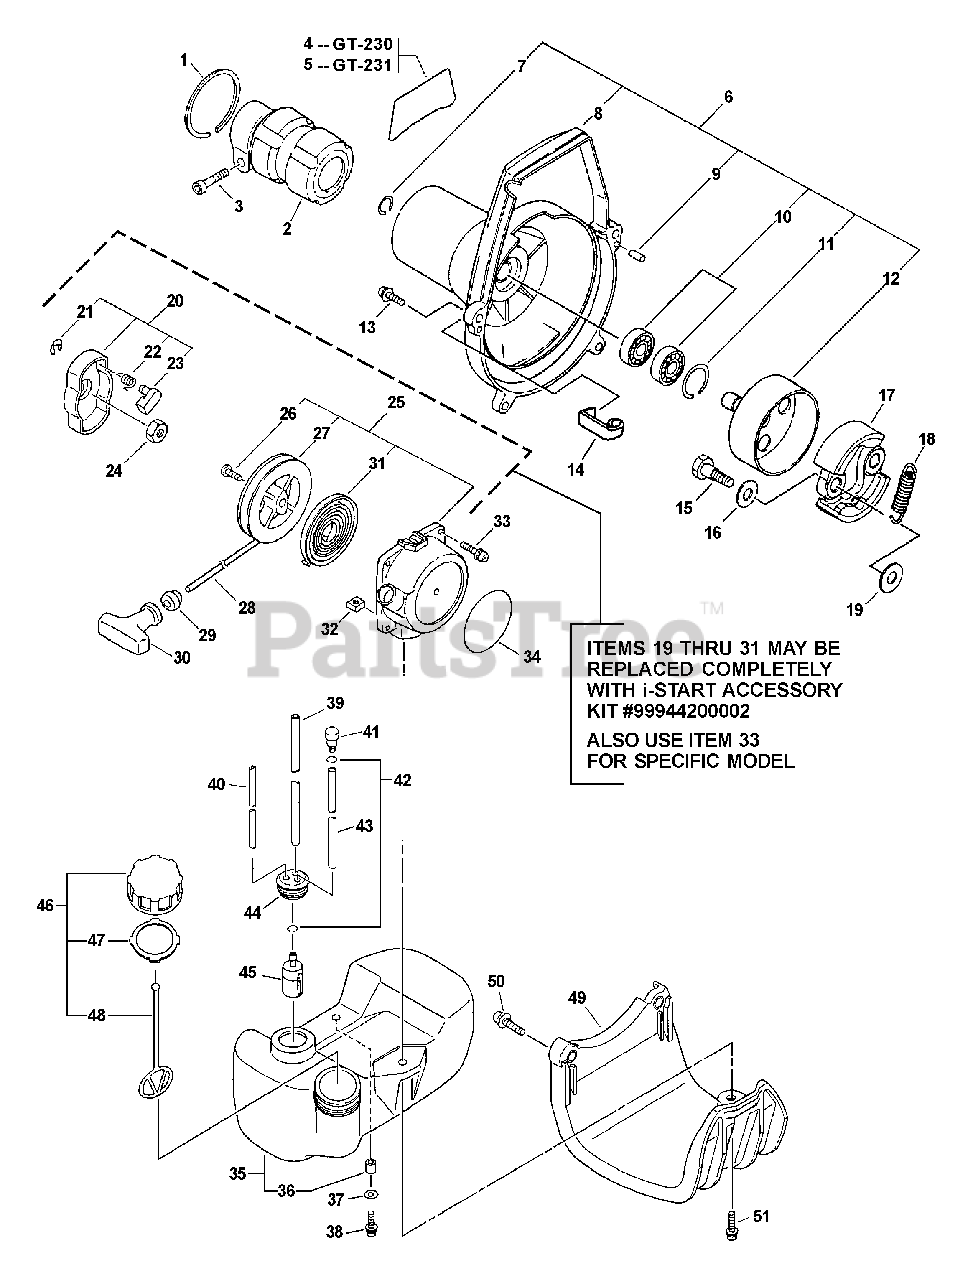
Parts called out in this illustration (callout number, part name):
1	RING, RETAINING - 42
2	CLAMP, MAIN PIPE
3	SCREW - 5X28
4	LABEL - MODEL GT-230
5	LABEL - MODEL GT-231
6	FAN CASE ASSY - GRAY
7	RING, RETAINING - 12
8	CASE, FAN - GRAY
9	PIN - LOCATING
10	BEARING, BALL - 6001
11	RING, RETAINING - 28
12	DRUM, CLUTCH
13	SCREW - 5X18
15	BOLT, CLUTCH
16	WASHER - SPRING
17	SHOE, CLUTCH
18	SPRING, CLUTCH
19	WASHER - 6
20	STARTER PAWL ASSY
21	RING, RETAINING - 4
22	SPRING, RETURN
23	PAWL, STARTER
25	STARTER ASSY
27	REEL, ROPE
28	ROPE, STARTER - 3.5X850
29	GUIDE, ROPE
30	GRIP, STARTER
31	SPRING, REWIND
32	NUT - 5 -- SQUARE
33	SCREW - 4X12
34	LABEL - ECHO
35	FUEL TANK ASSY
37	WASHER - 5
38	SCREW - 5X16
39	PIPE - 3X6X170 -- BLACK
40	PIPE - 3X6X80 -- CLEAR
41	VENT, FUEL TANK
42	CLIP - 6.5
43	PIPE - 3X6X115 -- BLACK
44	GROMMET
45	FILTER, FUEL
46	CAP ASSY - ORANGE
47	GASKET, CAP
48	CONNECTOR, CAP
49	GUARD, FUEL TANK
50	SCREW - 5X22
51	SCREW - 5X20
